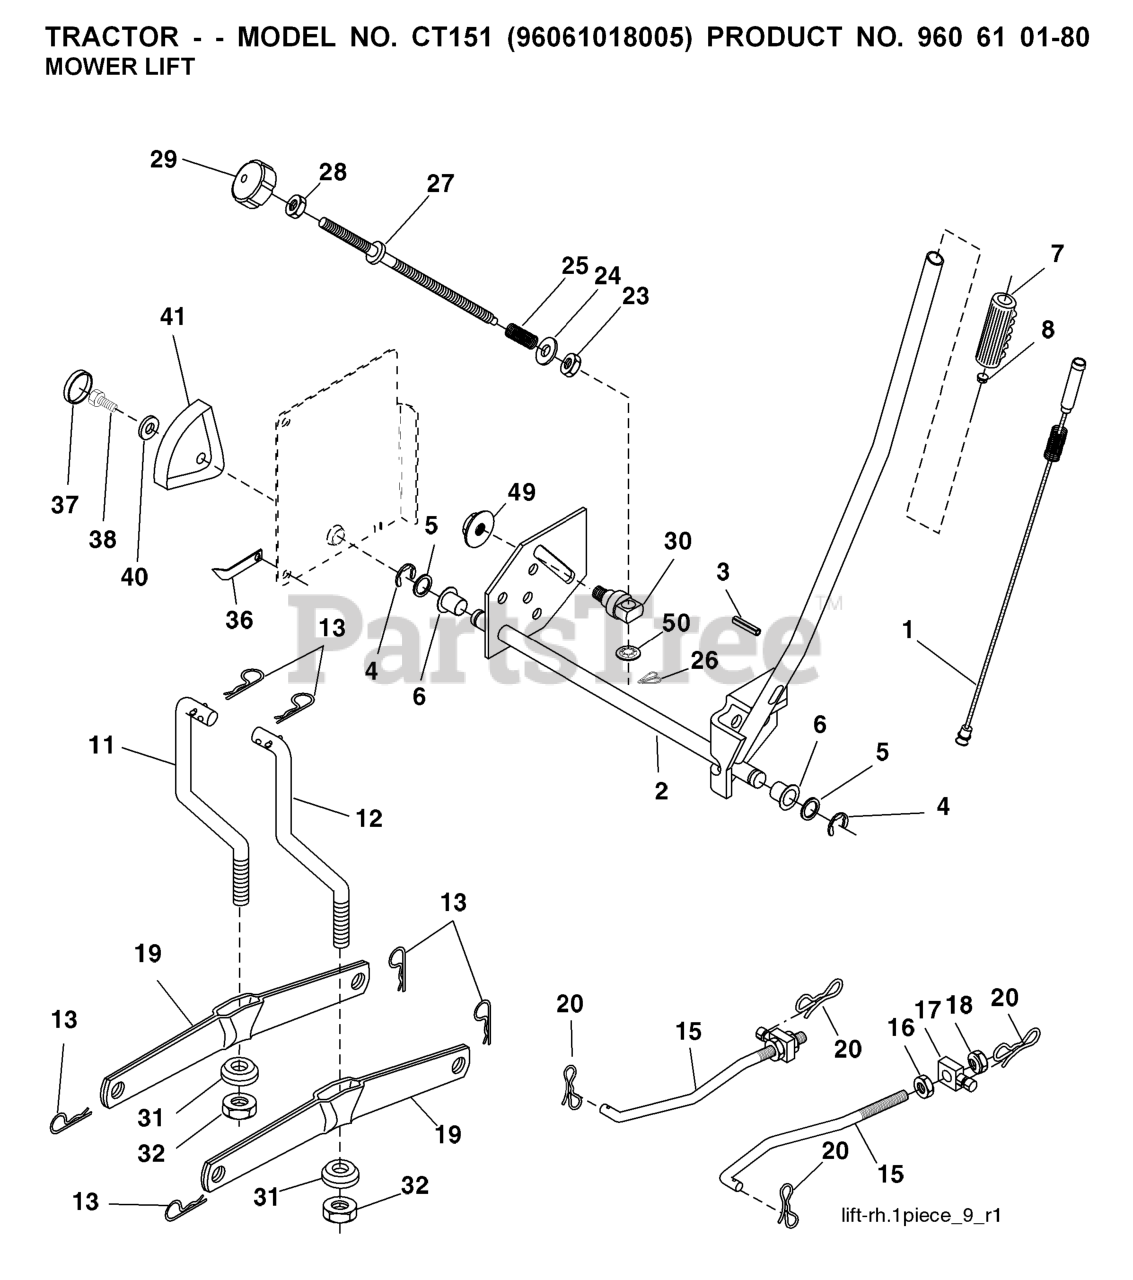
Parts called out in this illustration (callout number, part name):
1	WIRE ASM INNER W/ PLUNGER LT
2	SHAFT ASM R HANDLE
3	PIN GROOVE.
4	RETAINING RING LT
6	BEARING.NYLON
7	GRIP HANDLE
8	REPL BY 532 12 59-25
11	LINK
12	LINK
13	RETAINER-SPRNG RB
15	LINK.SUSPENSION.FRONT
16	NUT.HEX.JAM.1/2-13
18	NUT.LK.W/WSH.1/2.
19	ARM.REAR.SUSPENSION
20	PIN.COTTER.7/16.BOW TI.
26	RETAINER CLIP
27	ROD ADJ LIFT
28	NUT
29	KNOB INF 3/8-16
31	BEARING.PIVOT.LIFT
32	NUT CROWNLOCK 3/8-24
36	POINTER, HEIGHT INDICATOR(2 2)
38	SCREW 5/16-18X1
41	HEIGHT INDICATOR
49	NUT
50	NUT PUSH M
